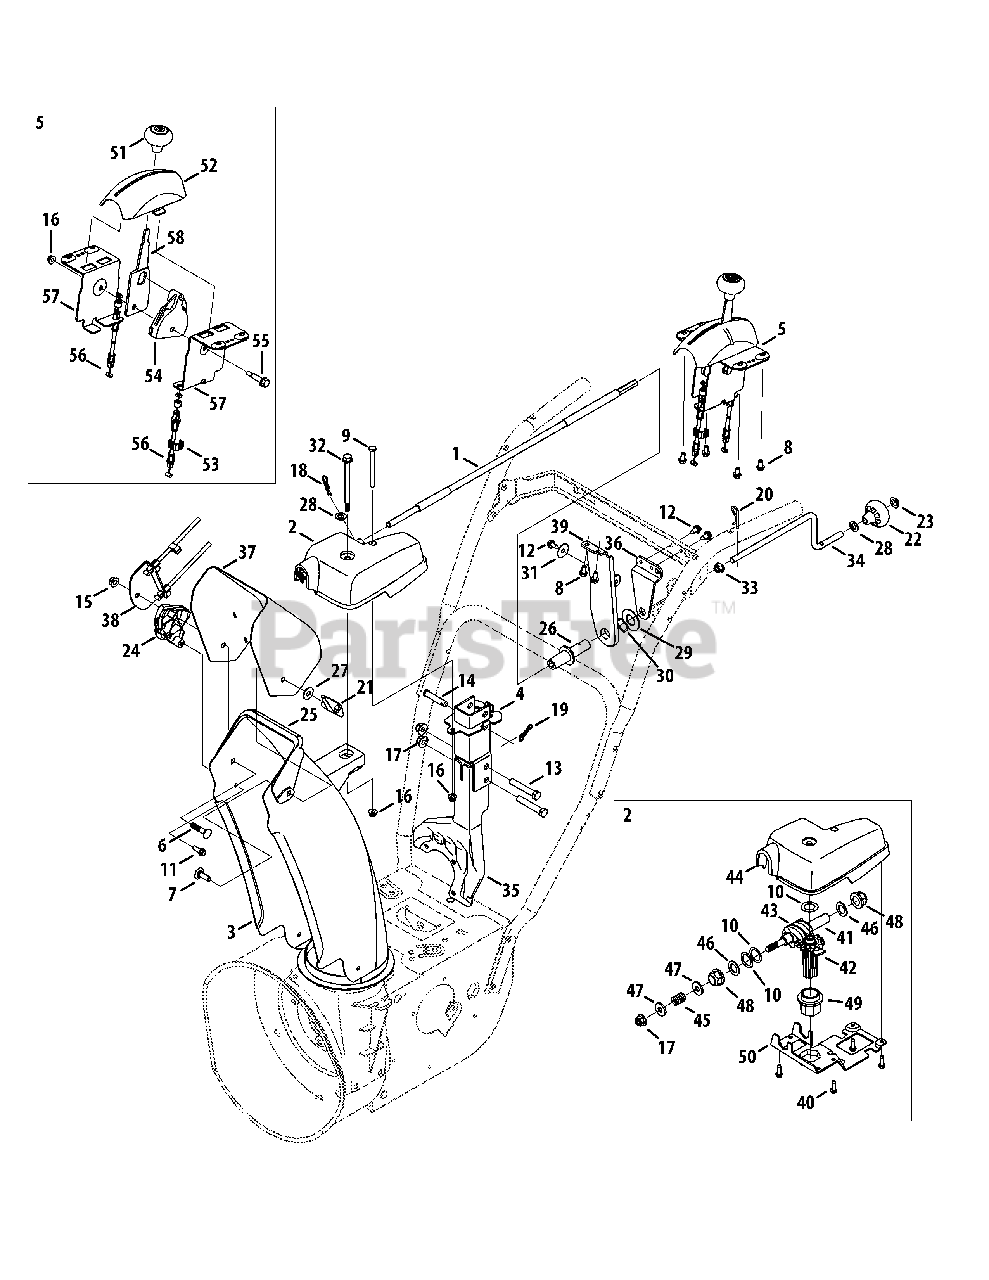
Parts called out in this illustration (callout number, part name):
1	Control Assembly
2	Chute Rotation Gearbox
4	Support Bracket Extension
5	Chute Control, 2-Way
6	Bolt, Carriage, 5/16-18 x 1.50
7	Bolt, Carriage, 5/16-18 x 1.00
8	Screw, HL, 1/4-15 x 0.50
9	Hex Head Screw, 1/4-20 x 3.00
10	Shim Washer, .632 x 1.00 x .010
11	Screw, HL, 1/4-15 x 0.750
12	Hex Washer Screw, 1/4-20 x .625
13	Hex Cap Screw, 3/8-16 x 2.25
14	Clevis Pin, 3/8 x 1.87
15	Nut, Flangelock, 5/16-18
16	Nut, Flangelock, 1/4-20
17	Flange Lock Nut, 3/8-16
18	Internal Cotter Pin
19	Bow-Tie Cotter Pin
20	Internal Cotter Pin
21	Wing Knob, 5/16-18
23	Push Cap, 3/8
24	Chute Cable Guide
25	Chute Adapter
26	Chute Control Rod Coupling
27	Washer, Flat, .349 x .879
28	Flat Washer, .375 x .738 x .063
29	Flat Washer, .78 x 1.59 x .06
30	Washer, Wave, .785 x 1.0 x .012
31	Flat Washer, .265 x 1.00 x .030
32	Screw, Shoulder, .312 x 3.5 x 1/4-20
33	Plastic Bushing, .38
35	Chute Support Bracket
36	Support Rod Bracket
38	Cable bracket
39	Chute Control Support Bracket
40	Screw, 12-16 x .75
42	Gear Assembly
43	Worm
45	Compression Spring, .39 x .60 x .88
46	Flat Washer, .625 x 1.0 x .067
47	Flat Washer, .380 x .93 x .110
48	Hex Bearing
49	Flange Bearing
51	Shift Knob
52	Cover, Tilt Cover
53	Cable Clip
54	Chute Tilt Cable Guide
55	Screw, Shoulder, .31 x .995:1/4-20
56	Cable, Chute Tilt
57	Bracket, Mounting
